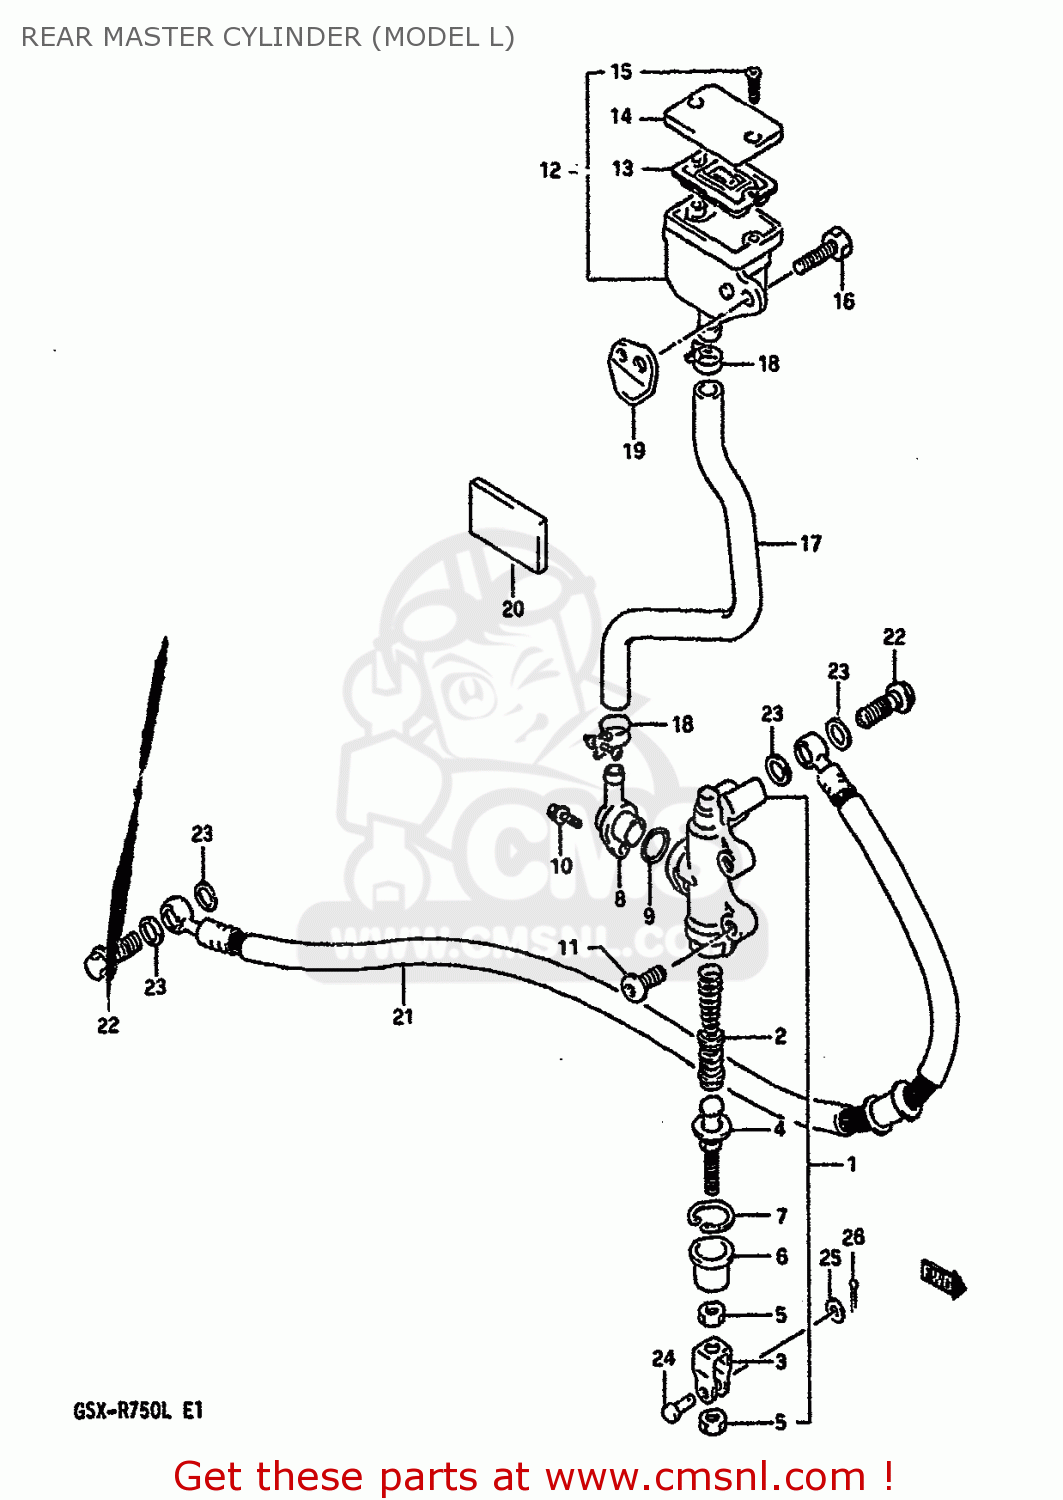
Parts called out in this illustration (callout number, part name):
1	CYLINDER ASSY,RR MASTER
2	PISTON/CUP SET
3	YOKE
4	ROD,PUSH
5	NUT
6	BOOT
7	CIRCLIP
8	CONNECTOR
9	O RING
10	SCREW
11	SCREW(8X22)
12	TANK ASSEMBLY,RESERVOIR
13	DIAPHRAGM
14	CAP
15	SCREW
16	BOLT
17	HOSE,RESERVOIR TANK
18	CLAMP
19	BRACKET,RESERVOIR TANK RR
20	CUSHION,PANEL
21	HOSE,REAR BRAKE
22	BOLT UNION
23	WASHER(10X15X1.5)
24	PIN
25	WASHER
26	PIN
